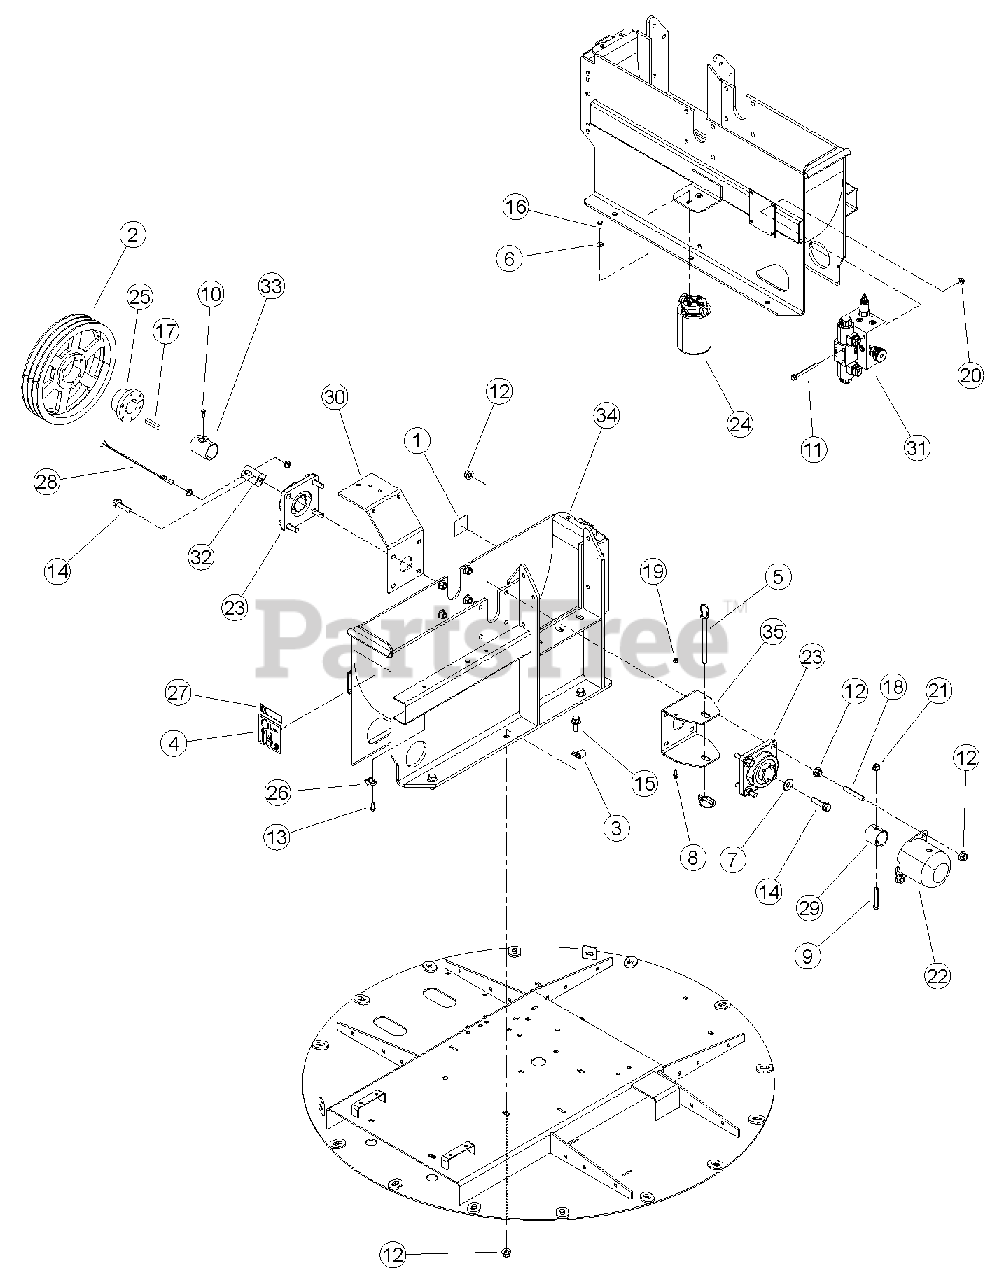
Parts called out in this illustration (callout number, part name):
1	DECAL, SHIELD DANGER ISO
2	SHEAVE, 3BQ12.4, SK
3	CLAMP, 9/16 COATED
4	DECAL, 114 DB (CE COMPLIANT ONLY)
5	PIN, HITCH 1/2 X 6-1/2 W/ LYNCH
6	WASHER, 1/4" FLAT ZP
7	WASHER, 1/2" FLAT ZP
8	BOLT, 1/4-20 X3 /4 HWH GR5 CZP
9	BOLT, 3/8 X 2-1/2 GR5 HHCS ZP
10	SCREW, 5/16-18 X 5/8 SQ HD SET
11	BOLT, 5/16 X 3-1/2 SERRATED FLANGE NC
12	NUT, 1/2-13 NYLOCK FLANGE
13	SCREW, 11/32 X 7/8 HWH AB THREAD ZP
14	BOLT, 1/2-13 X 2 HWH GR5 CZP
15	BOLT, 1/2 -13 X 1-1/4 FLANGE NC
16	BOLT, 1/4 X 5/8" HHCS GR5 ZP
17	KEY, 3/8" SQ X 2" LG PLAIN
18	STUD, 1/2"-13 X 3" LG B7 ZP
19	NUT, 1/4-20 NYLOCK-FLANGE
20	NUT, 5/16-18 NYLOCK-FLANGE
21	NUT, 3/8-16 NYLOCK FLANGE
22	CAP, LARGE SHAFT
23	BEARING, 1-3/4 4 BOLT FLANGE
24	ASSEMBLY, HYDRAULIC FILTER
25	BUSHING, SK 1-3/4"
26	CLAMP, CABLE MOUNT
27	DECAL, CH8720IH INFORMATION (CE COMPLIANT ONLY)
28	SENSOR, M12 PNP PROXIMITY (REPLACEMENT PART)
29	COLLAR, CHIPPER LOCK
30	WELDMENT, REAR GUARD SUPPORT
31	ASSEMBLY, HYDRAULIC FEED FLOW VALVE W/ PS
32	BRACKET, PROXIMITY SENSOR
33	WELDMENT, SPACER 2.0 X 2.30
34	WELDMENT, CHIPPER BOTTOM
35	BRACKET, ROTOR LOCK
